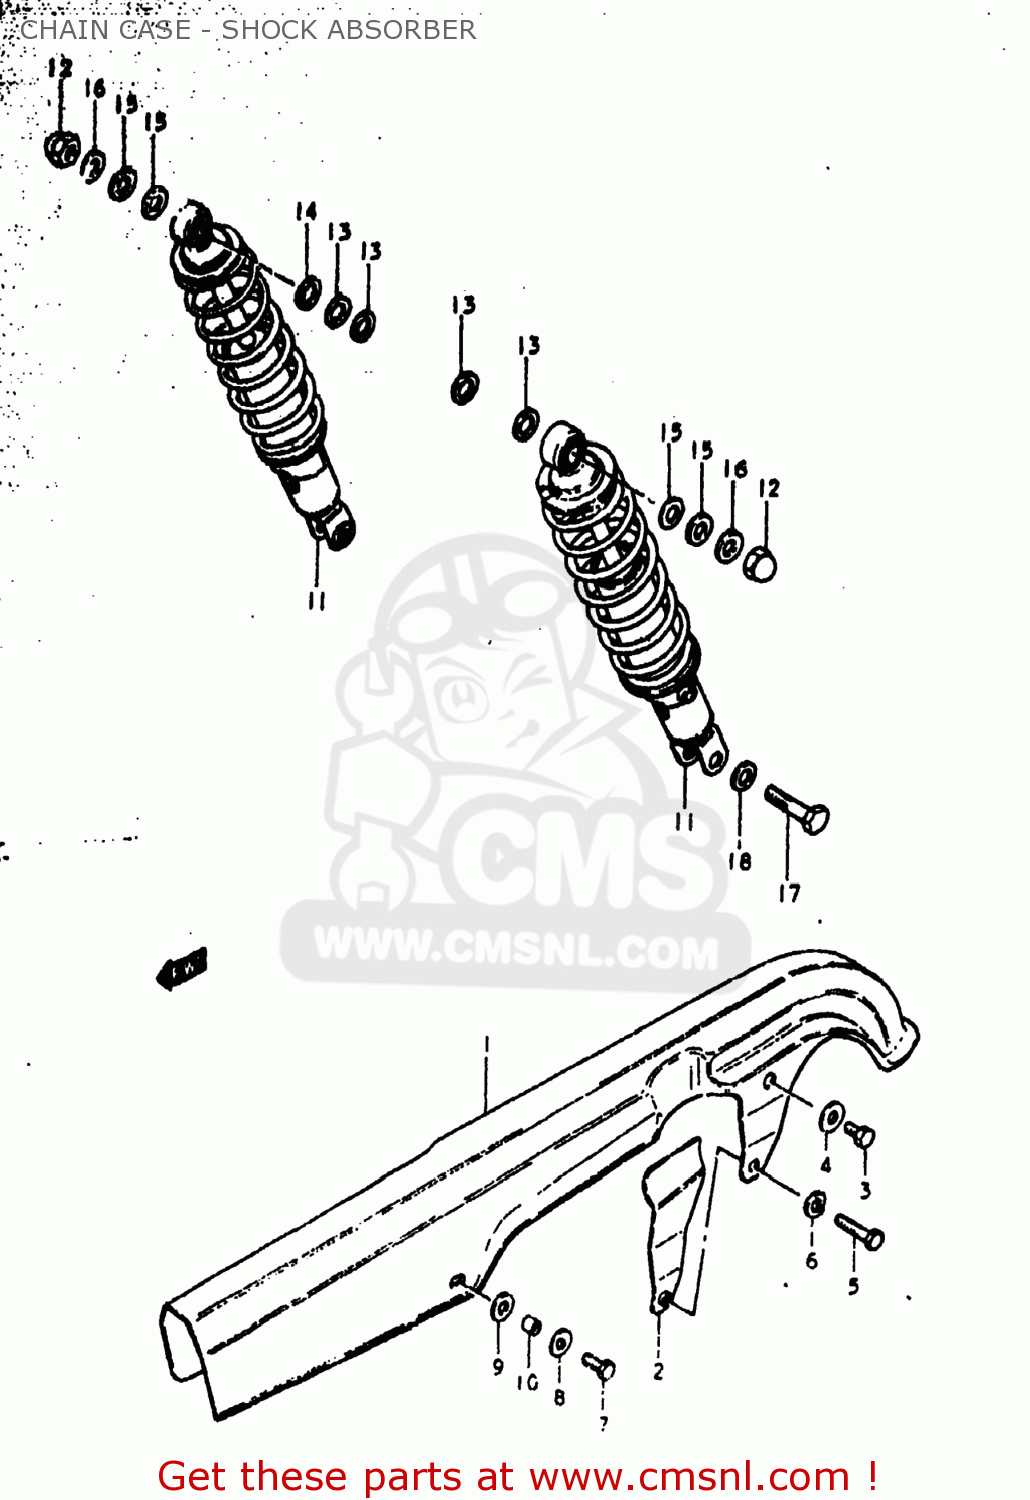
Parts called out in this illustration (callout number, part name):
1	CASE,CHAIN
2	REINFORCEMENT,CHAIN CASE
3	BOLT(6X8)
4	WASHER
5	BOLT
6	LOCK WASHER
7	BOLT
8	WASHER(6.5X18X1)
9	CUSHION
10	SPACER (6.1X8X5.2)
11	ABSORBER ASSEMBLY,REAR SHOCK
12	NUT, LOWER LH
13	WASHER
14	WASHER (12.5X24X3.2)
15	WASHER
16	WASHER(10.5X24X3.2)
17	BOLT(10X36)
18	WASHER
